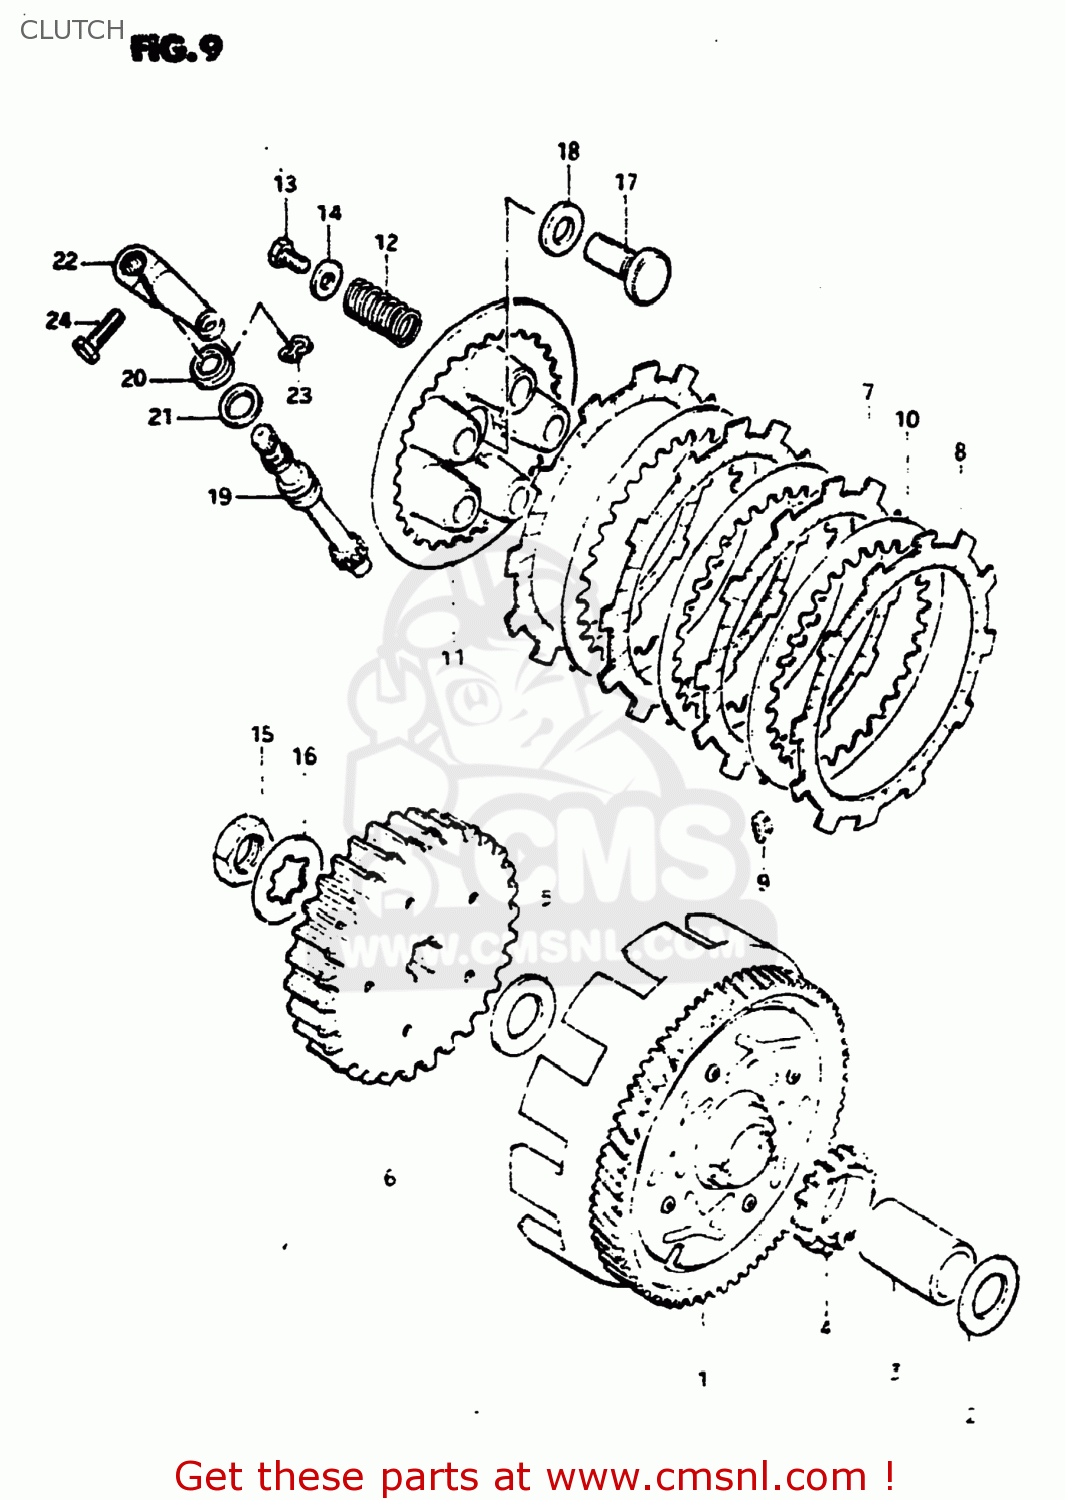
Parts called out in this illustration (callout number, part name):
1	GEAR ASSY,PRI DRIVEN(NT:73)
2	WASHER,THRUST
3	SPACER
4	GEAR,KICK STARTER DRIVE
5	WASHER
6	HUB,CLUTCH SLEEVE
7	PLATE,CLUTCH DRIVE
8	PLATE,CLUTCH DRIVE (NAS)
9	DAMPER
10	PLATE,CLUTCH DRIVEN (NAS)
11	DISC,CLUTCH PRESSURE
12	SPRING
13	BOLT(5X16)
14	WASHER (5.5X16X1.2)
15	NUT
16	WASHER,LOCK
17	RACK,CLUTCH RELEASE
18	BEARING(10X22X2.8)
19	PINION,CLUTCH RELEASE
20	OIL SEAL
21	WASHER (12X17X1)
22	ARM,CLUTCH RELEASE
23	WASHER
24	BOLT, UPPER
